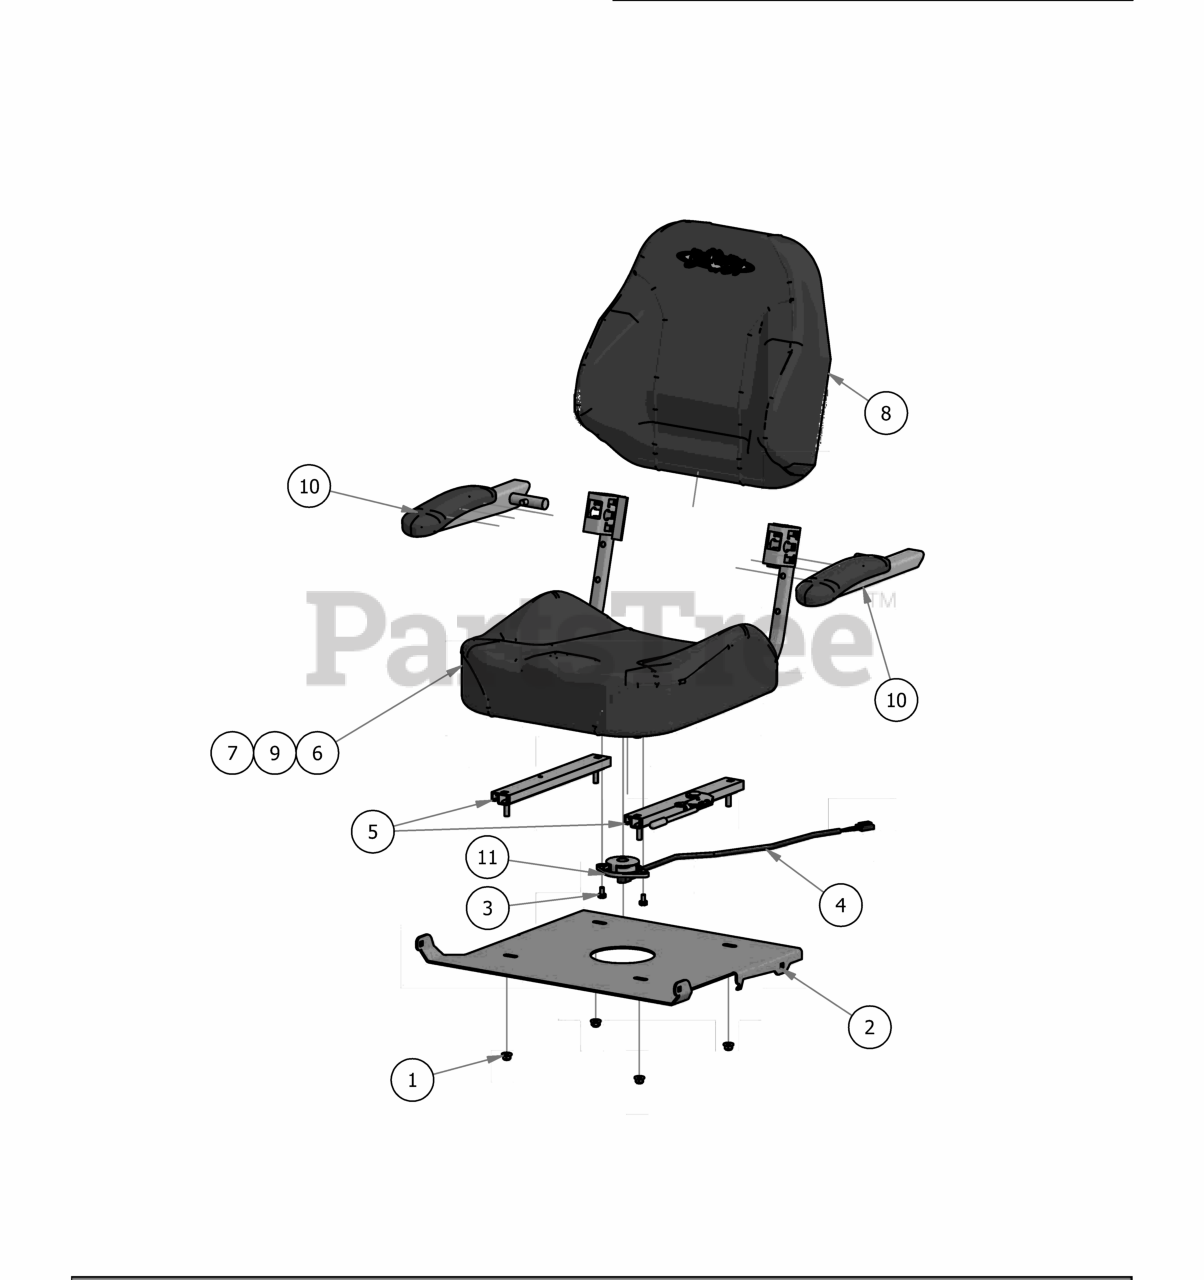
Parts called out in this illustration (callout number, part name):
1	5/16" Nylon Flange Nut
2	Seat Plate 2016
3	1/4-20x1/2 HWH Bolt Slot
4	Seat Switch Adapter
5	Seat Rail Pair
6	2017 ZT Seat
8	Seat Back Cushion
9	Seat Bottom Cushion
11	Seat Safety Switch
